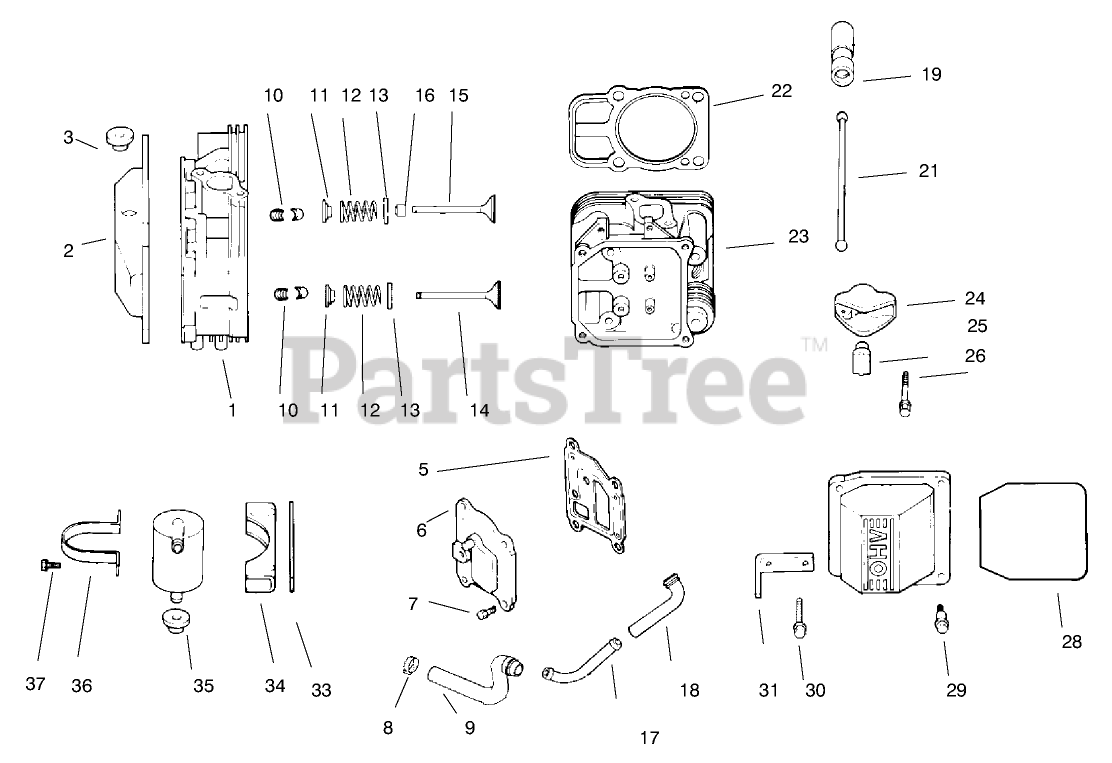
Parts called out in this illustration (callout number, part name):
1	#1 Cyl. Head Asm
2	Kit-Valve Cover& Breather (Incl. Ref.# 3,& 28-29)
3	Grommet-Rubber
5	Gasket-Breather
6	Cover-Breather
7	Screw
8	Clamp
9	Hose-Breather
10	Retainer Kit
11	Cap-Spring, Valve
12	Spring-Valve
13	Retainer-Spring
14	Valve-Exhaust
15	Valve-Intake
16	Seal-Stem, Valve
17	Fitting
18	Hose-Breather
19	Lifter-Valve
21	Rod-Push
22	Gasket-Cylinder Head
23	#2 Cyl. Head Asm,
24	Arm-Rocker
25	Pivot-Arm, Rocker
27	Kit-Valve Cover (Incl. Ref.# 28-29)
28	O Ring
29	Screw
30	Screw
31	Strap-Lifting
33	Spacer
34	Bracket
35	Grommet-Rubber
36	Strap-Lifting
37	Screw-HF
